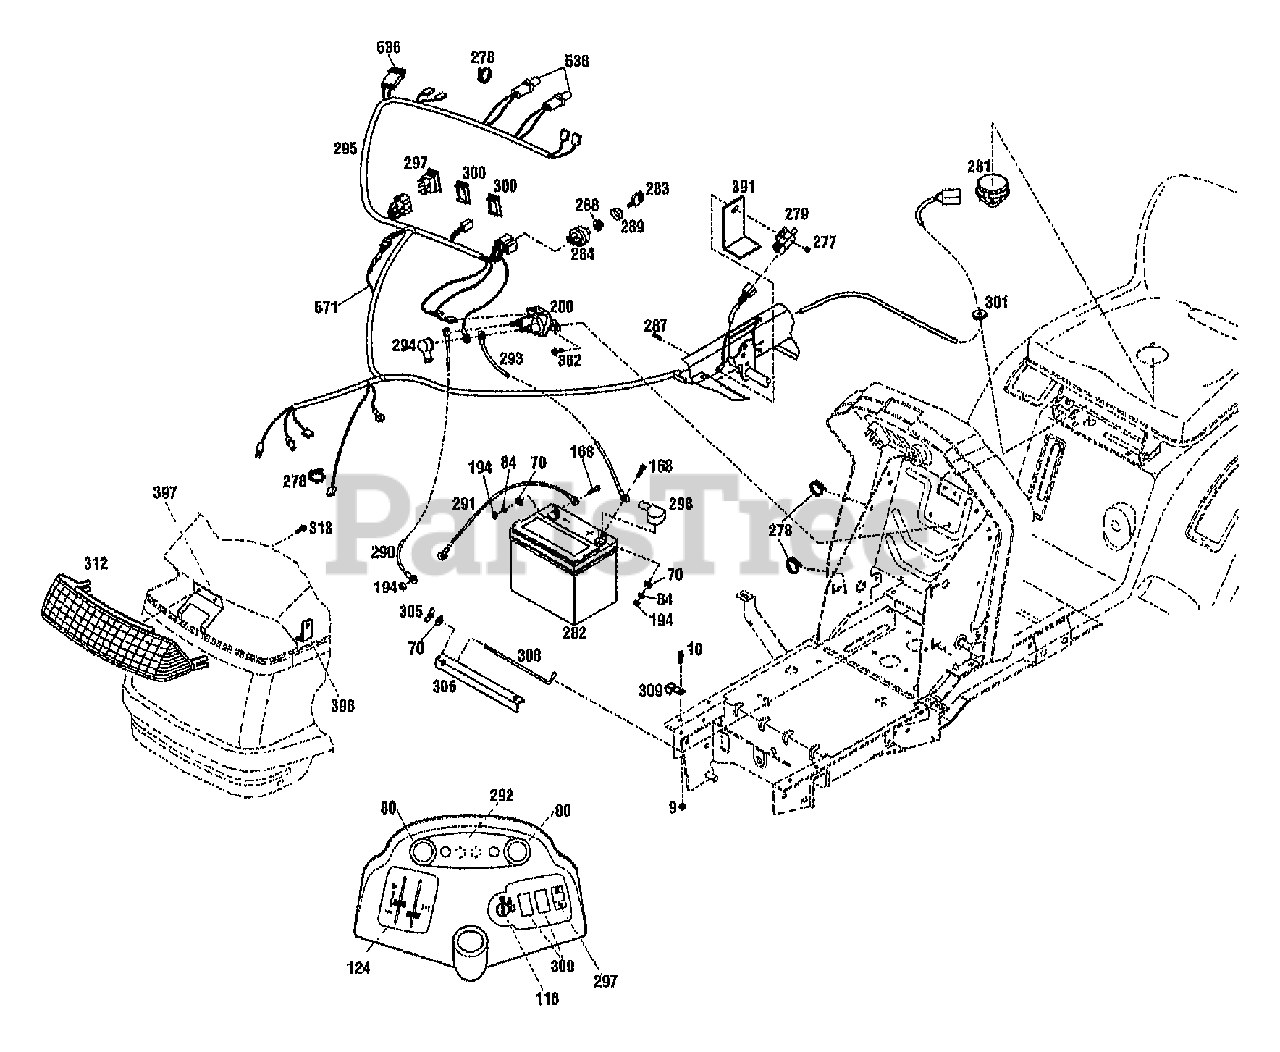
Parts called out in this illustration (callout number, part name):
9	NUT-HFLK 5/16-18 ZP
10	SCR-HHC 5/16-18X.75 GR 5 ZP
70	WASHER-FLAT 1/4 SAE
84	WASHER-LK .25 ZP
116	DECAL-IGNITION
124	DECAL-CONTROL
168	SCR-HH 1/4-20X.75 G5 ZP
194	NUT-HEX 1/4-20 ZP
277	NUT W/LKWASHER 10-24 ZP
278	TIE-CABLE NYLON BLACK
279	SWITCH
280	SOLENOID
281	SWITCH-SEAT
282	BATTERY
283	KEY-IGNITION
284	SWITCH-IGNITION
287	SCR-HHS 10-24X.625 ZP
288	NUT-SWITCH
289	CAP-SWITCH
290	CABLE-STARTER
291	CABLE-BATTERY (-)
292	LENS (WARNING)
293	CABLE-BATTERY
294	BOOT-SOLENOID
295	HARNESS-MAIN
297	SWITCH-PTO
298	BOOT-TERMINAL
300	COVER-SWITCH
301	GROMMET
305	NUT-WING
306	CLAMP-BATTERY
308	SCR-HOOK
309	CLIP-J
312	LENSE-HEADLIGHT
362	SCR 1/4-20X.5 FL SELF TAP
391	BRACKET-SWITCH
397	RETAINER-LENS
398	CLIP-RETAINING
536	FUSE
538	LIGHTBULB
571	ASSM-DIODE
